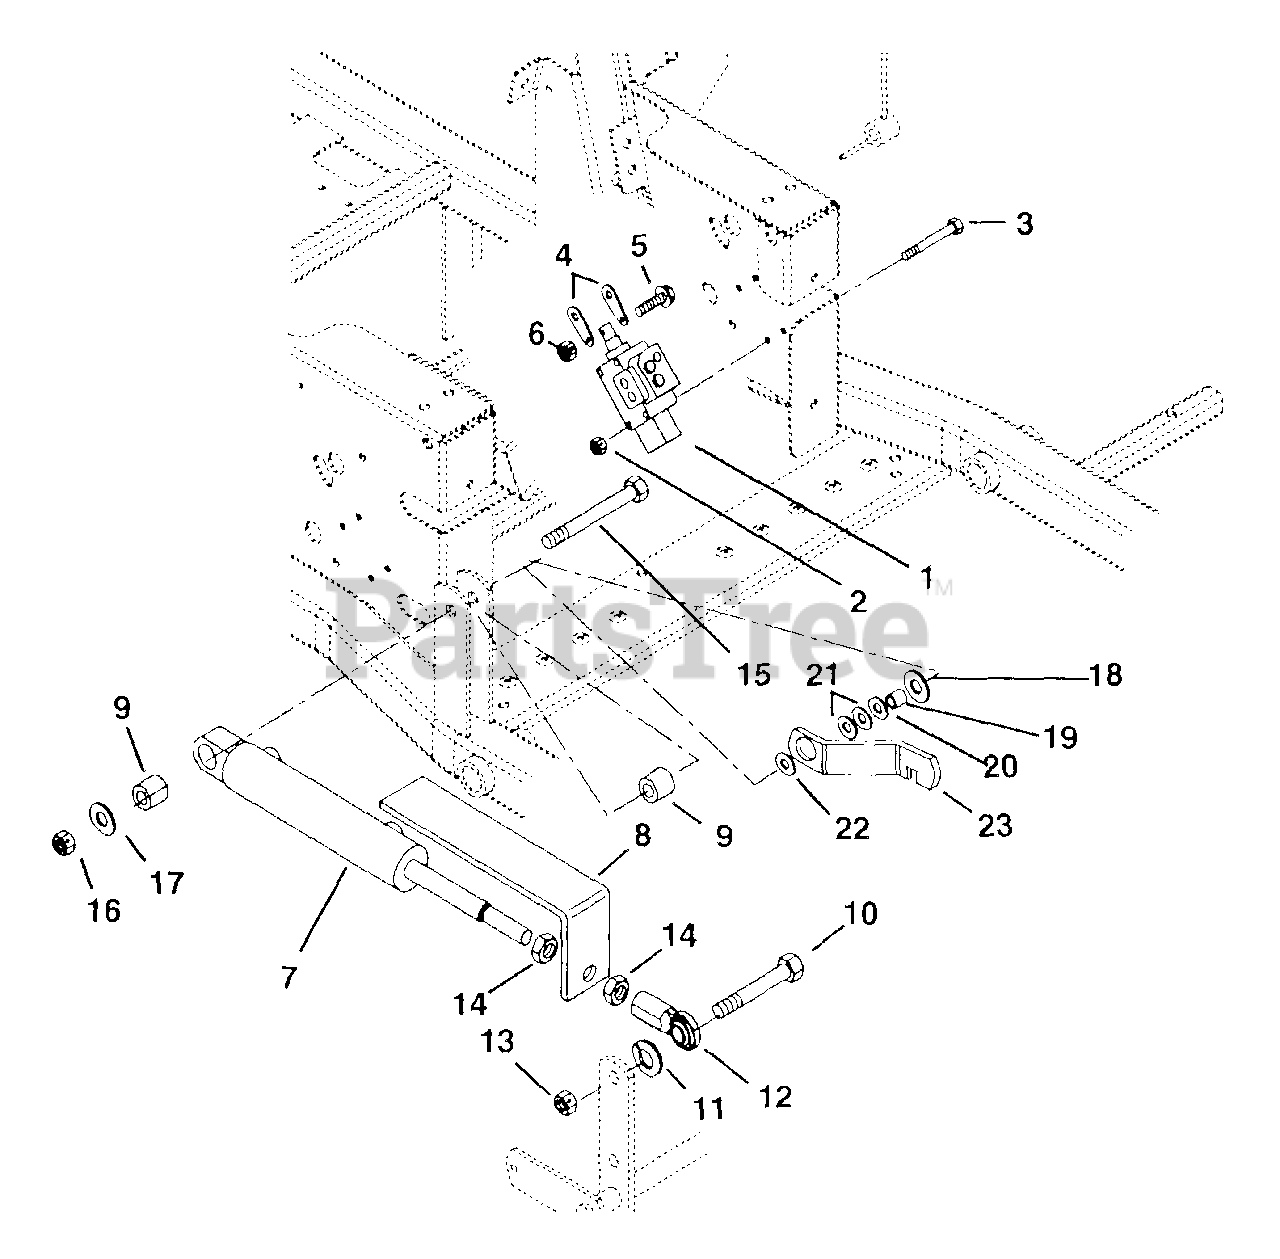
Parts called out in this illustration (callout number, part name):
1	Valve, Hydraulic Lift
2	Nut-Locking-Nylon .25-20
3	Bolt-Hex .25-20 x 2.75 Grade 5
5	Screw-Machine 10-24 x 1.00 Hex Washer Head
6	Nut-Locking-Nylon 10-24 with Insert
7	Cylinder-Hydraulic Lift
8	Strap-Height of Cut indicator
9	Bushing .516 x 1.000 x 1.050
10	Bolt-Hex .62-11 x 2.25 Grade 8
11	Washer-Lock .62 x .156
12	Rod End-Right Hand-Female 5/8
13	Nut-Locking-Center .62-11
14	Nut-Jam .625-18
15	Bolt-Hex .50-13 x 3.75 Grade 5
16	Nut-Locking-Center .50-13
17	Washer-Flat-Steel .515 x 1.625 x .250
18	Washer-Flat-Steel .531 x 1.06 x .095
19	Spacer .500 x .750 x .321
20	Washer-Flat-Steel .754 x 1.000 x .032
21	Washer-Flat-Steel .754 x 1.125 x .062
22	Wave-Washer
